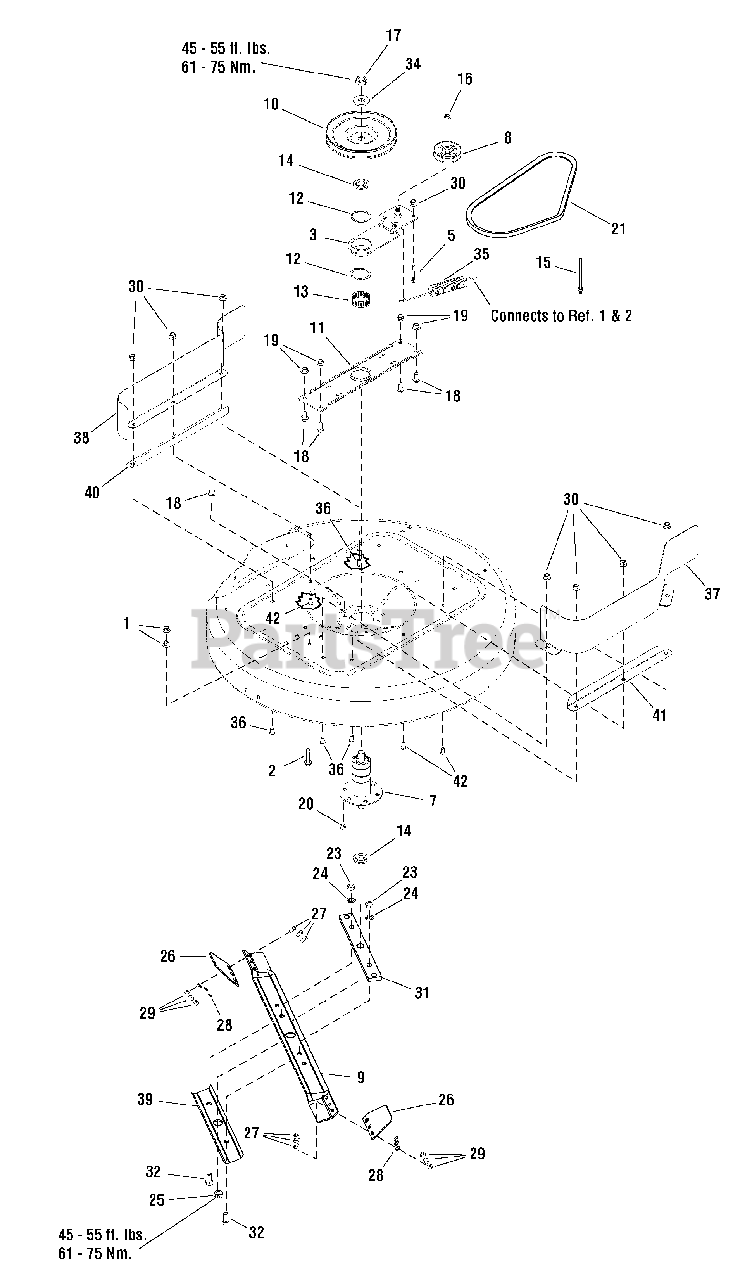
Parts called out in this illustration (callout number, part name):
1	NUT, 5/16-18
2	BOLT, 5/16-18 x 2.0
3	BLADE, Idler Bracket
5	BELT GUIDE
7	SPINDLE ASSY
8	IDLER PULLEY
9	BLADE, 33"
10	PULLEY, 33" Input
11	BRACE, Spindle
12	RING, Retaining
13	TOLERANCE RING
14	WASHER, Spindle
15	BELT GUIDE, Long
16	NUT, Flange 3/8-16
17	NUT, Hex, Jam, 3/4F GR8
18	BOLT, Hex 3/8-16 x 3/4
19	NUT, Hex Flange, 3/8-16
20	NUT, Centerlock, 3/8-16
21	BELT, 33" Blade Drive
23	NUT, Hex Jam, 1/2-20
24	WASHER, 1/2" Internal Tooth Lock
25	NUT, Hex Center Lock Jam, 5/8-18
26	33" AIR LIFT
27	SCREW, Oval Head, 5/16 - 24 x 21/32
28	WASHER, 5/16" Internal Tooth Lock
29	NUT, Hex, 5/16 - 24
30	NUT, Hex Flange 5/16-18
31	HOLDER, Blade
32	CAPSCREW, Hex Head, 1/2-20 x 1-1/4, GR5
34	WASHER, 25/32 x 1.5 x .132
35	SPRING, Extension PTO
36	BOLT, Carriage, 3/8-16 x 5/8
37	GUARD, L.H.
38	GUARD, R.H.
39	STIFFENER
40	BRACE, R.H.
41	BRACE, L.H.
42	CAPSCREW, Hex Whiz Lock, 5/16-18 x 3/4
